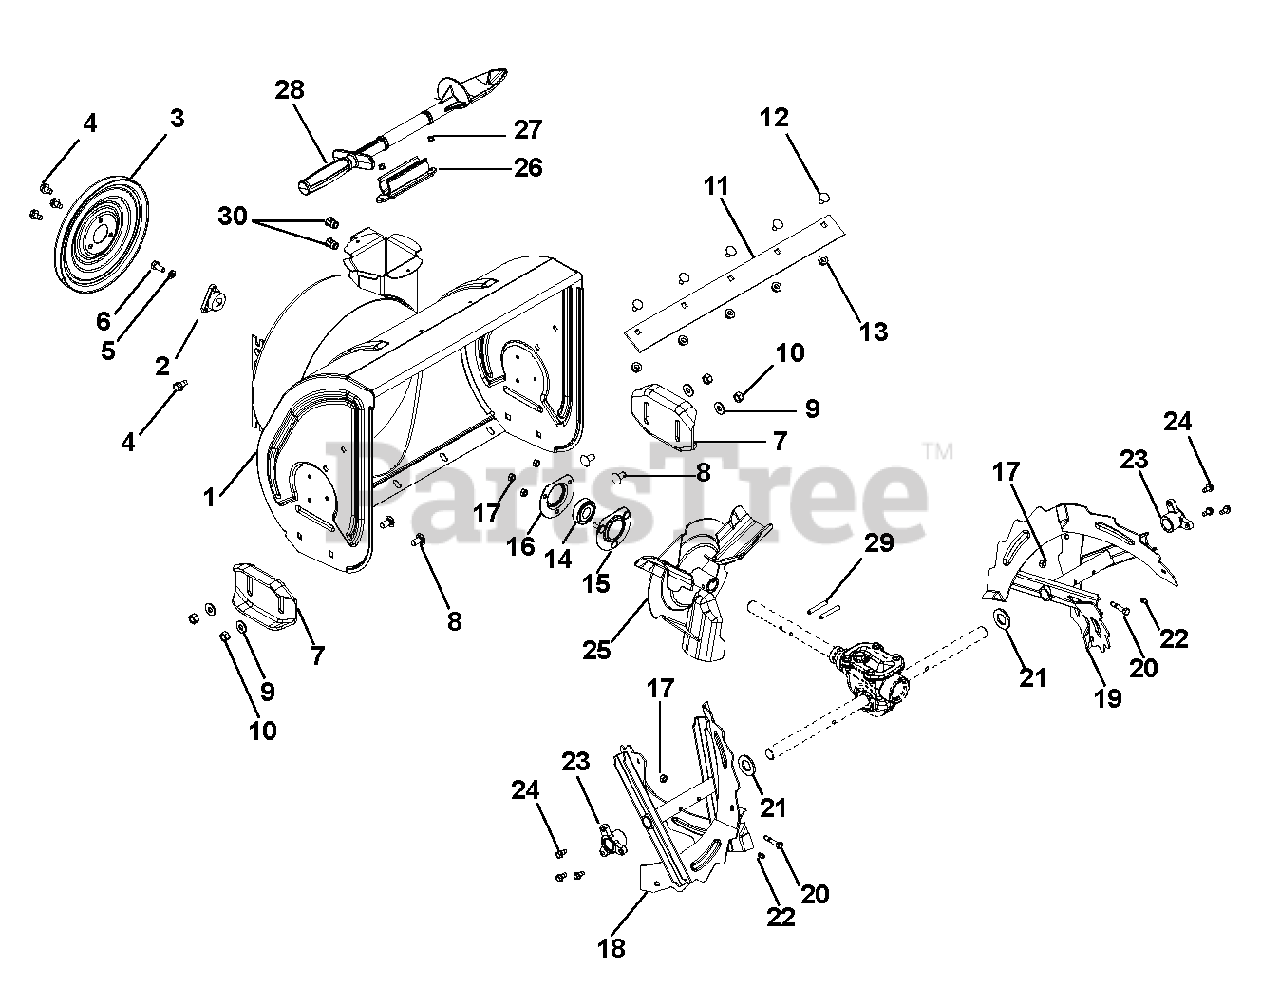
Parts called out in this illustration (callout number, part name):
1	BLOWER HOUSING, 20" BLACK
2	HUB, ATTACHMENT PULLEY D-BORE
3	PULLEY,SPIN FORM SINGLE GROOVE
4	@SCR-TAP .31-18X.50 HWH TR YWZ
5	WSHR-LK .312X.097 HVY YWZC
6	BLT-HEX .31-24X.75 YWZC GR5
7	SKID SHOE, REVERSIBLE - BLACK
8	@BLT-RHDSSQNK .38-16X.75 G5YZ
9	@WSHR-FL-STL.38X.875X.083 YWZC
10	@NUT-LK-CTR .38-16 YWZC
11	BLADE, SCRAPER 20" COMPACT BLK
12	BOLT, MODIFIED HEAD CARRIAGE
13	@NUT-LK-TOP-FLG .31-18 YWZC
14	BRG-BALL .750X1.750X.50
15	BEARING FLANGE
16	BEARING FLANGE
17	@NUT-LK-CTR .25-20 YWZC
18	AUGER, 20" RH, BLK SERR W/ZERK
19	AUGER, LH 20", BLK SERR W/ZERK
20	SHEAR BOLT WITH NUT
21	@WSHR-FL-STL.812X1.50X.135YWZC
22	ZERK,FITTING .25X.125 DRIVE IN
23	BUSHING, RAKE SHAFT .75"
24	SCR-TAP .25-20X.50 HWH TR YWZ
25	IMPELLER, COMPACT 12" 3-BLADE
26	MOUNT, SNOW CLEAN OUT
27	RVT-POP .187 YZ
28	DEVICE, SNOW CLEAN OUT
29	PIN-ROLL .250X1.75
30	NUT, THREADED INSERT .38-16
